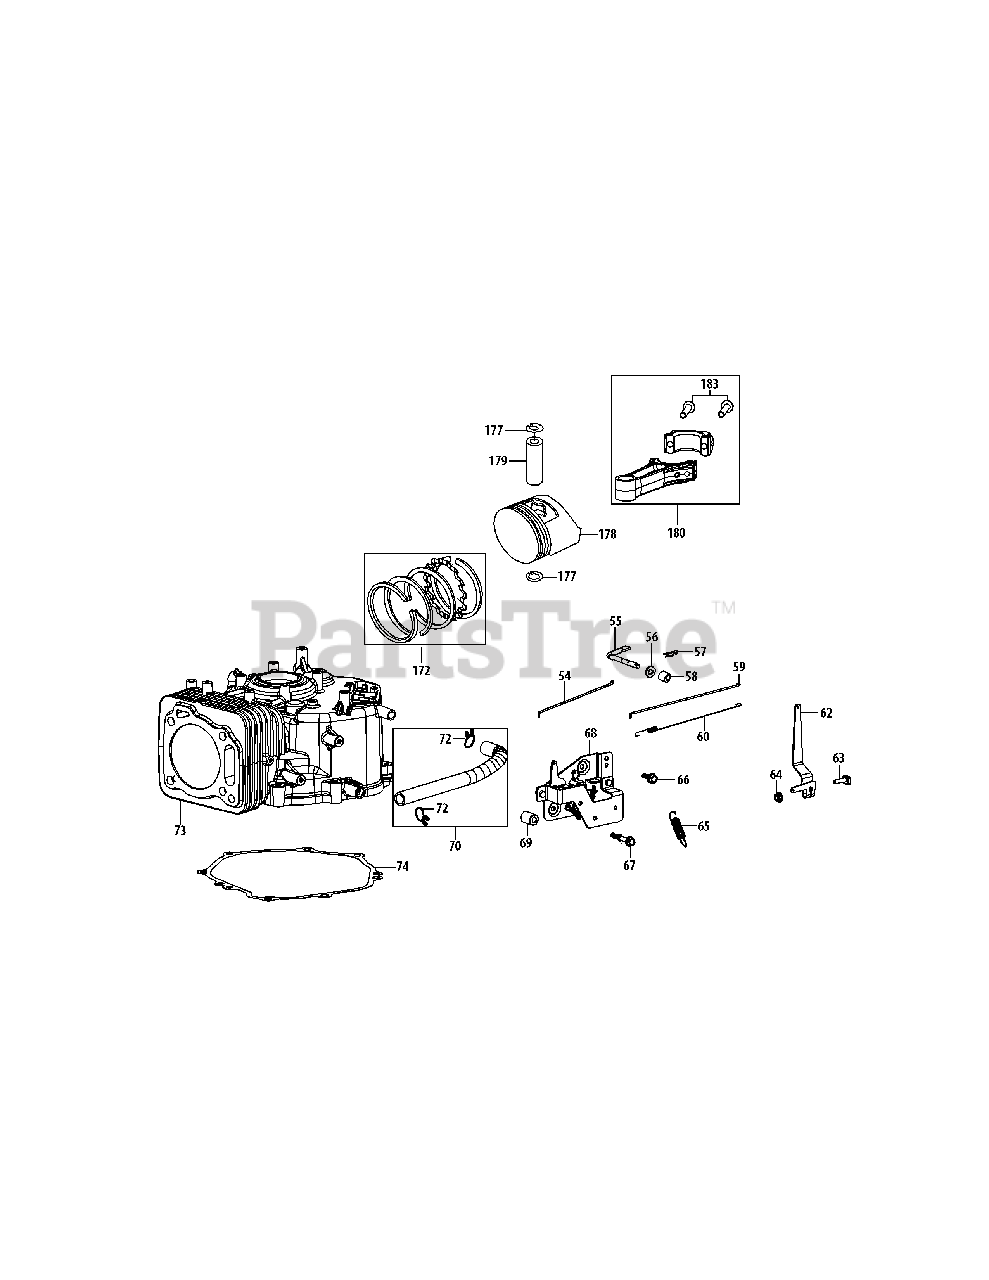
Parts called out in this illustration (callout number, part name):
54	Choke Linkage Rod
55	Governor Arm Shaft
56	Governor Washer
57	Governor Cotter Pin
58	Governor Seal
59	Throttle Linkage Rod
60	Throttle Linkage Spring
62	Governor Arm
63	Governor Arm Bolt
64	Governor Arm Nut M6
65	Governor Spring
66	Bolt M6×18
67	Bolt M6×38
68	Throttle Control Bracket
69	Component Bracket Spacer
70	Breather Hose Assembly
72	Breather Hose Clamp
73	Short Block Assembly
74	Crankcase Cover Gasket
172	Piston Ring Set Kit
177	Piston Pin Snap Ring
179	Piston Pin
180	Connecting Rod Assembly
183	Connecting Rod Bolt
